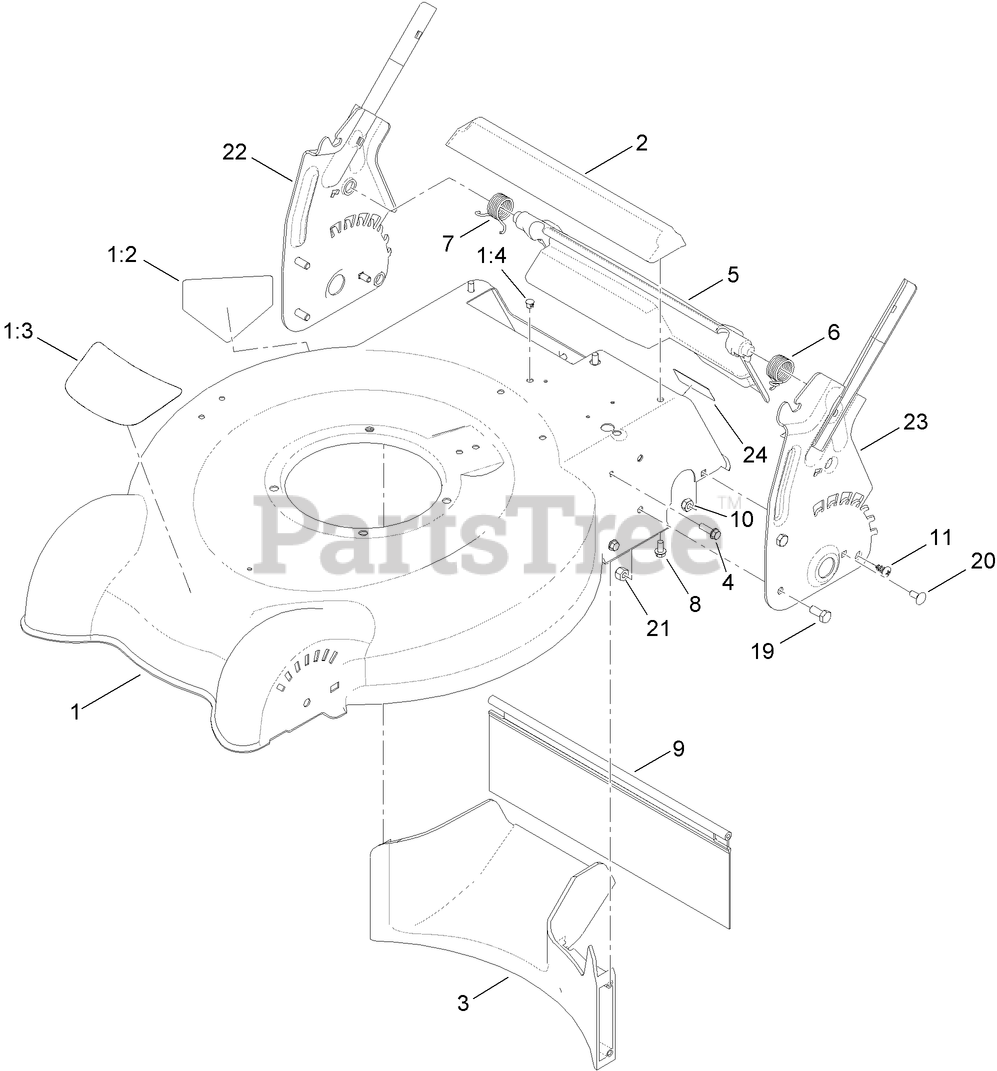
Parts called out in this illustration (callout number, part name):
1	HOUSING ASM
1:2	DECAL-DANGER
1:4	PLUG-DOME
2	CHUTE-REAR
3	BAFFLE-REAR
4	SCREW-HWH
5	REAR DEFLECTOR ASM
6	SPRING-TORSION, LH
7	SPRING-TORSION, RH
8	SCREW-PLASTITE
9	SHIELD-TRAILING
10	NUT-LOCK, NI
11	SCREW-PTH
19	SCREW-HH
20	SCREW-CARR
21	NUT-LOCK, NI
22	PLATE-HOC, LH
23	PLATE-HOC, RH
24	DECAL-LOCATION, SERVICE DEALER
